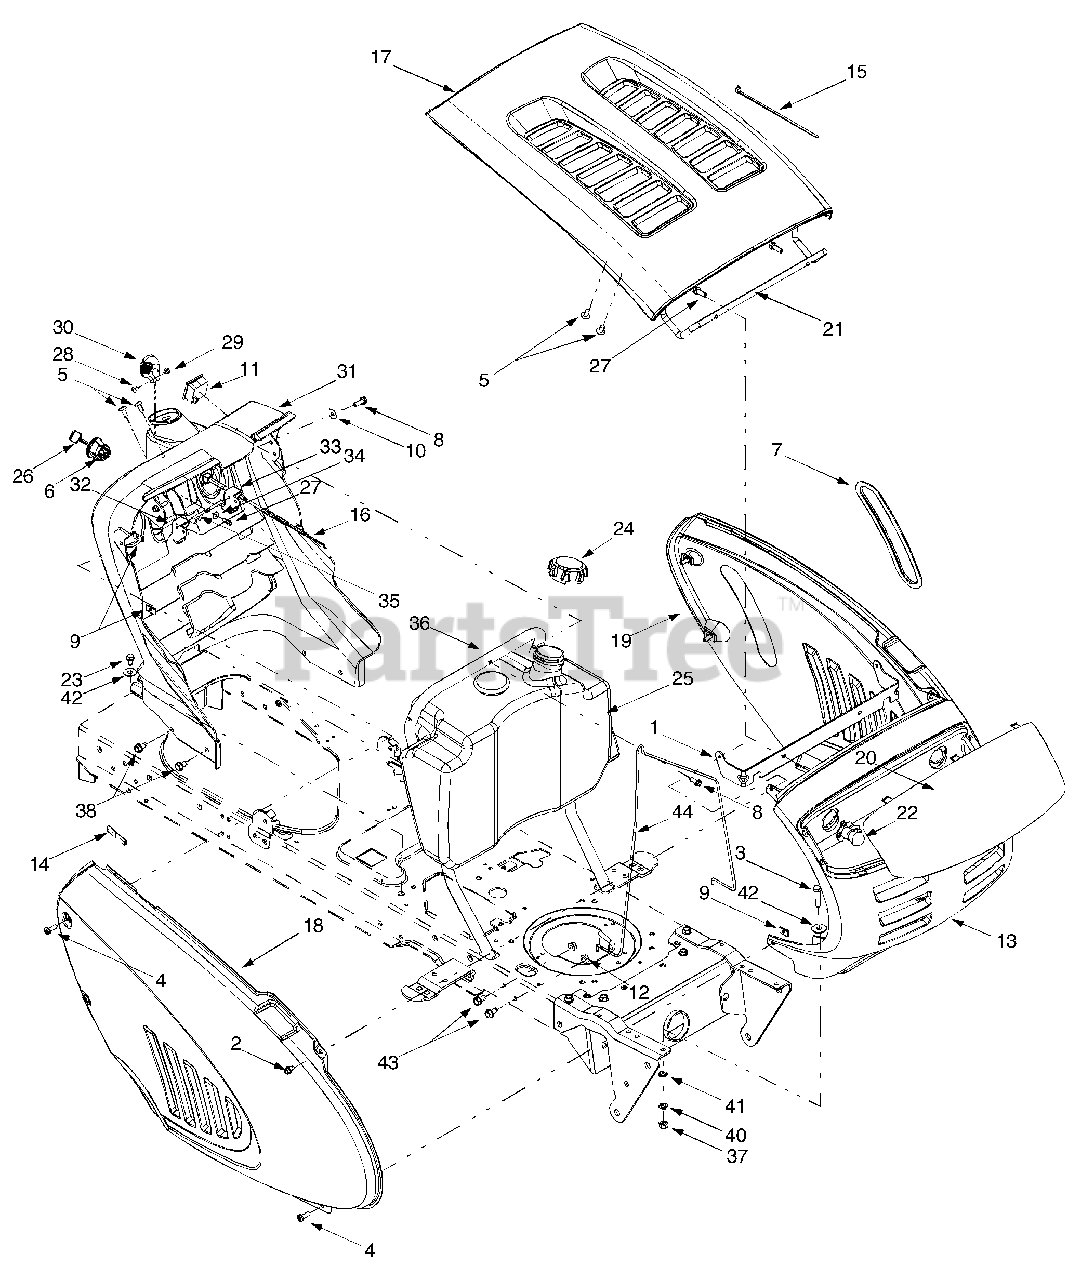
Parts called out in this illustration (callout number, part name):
2	Self-tapping Screw, 1/4-20 x .5
3	Hex Cap Screw, 5/16-18 x 1.25
4	Phillips Pan Screw, 1/4-20 x .75
5	Truss Phillips Screw, 1/4-20 x .625
6	Ignition Switch
7	Side Panel Seal
8	Self-tapping Screw, 1/4-20 x .75
9	U-type Speed Nut, 1/4-20
10	Bell Washer, .265 x .75 x .062
11	Systems Indicator Monitor
12	Hex Nut, 5/16-18
13	Grille (9-style)
14	Trim Strip, 4
15	Cable Tie, 3/16 x .05 x 7.4
16	Choke Knob/Cable (Model LTX-2146)
21	Hood Hinge Rod
22	Headlight Assembly
23	Self-tapping Screw, 5/16-12 x .75
24	Fuel Cap
25	Fuel Tank, Three-gallon
26	Ignition Key w/ plastic cover
27	Self-tapping Screw, 1/4-15 x .75
28	Truss Phillips Screw, #8-32 x .375
29	Hex Nut, #8-32
30	Throttle Control Knob
31	Dash Panel
32	Cruise Control Button
33	Parking Brake Button
34	Flat Washer, 9/32 x 1/2 x 1/16
35	Brake/Cruise Pivot Rod
36	Dash Support Tube
37	Hex Nut, 5/16-18
38	Self-tapping Screw, 5/16-18 x .75
40	Lock Washer, 5/16
41	Speed Nut, .3125
42	Flat Washer, .349 x 1.0 x .063
43	Screw, 5/16-18 x .875 (Grade 5)
44	Fuel Tank Support Rod
